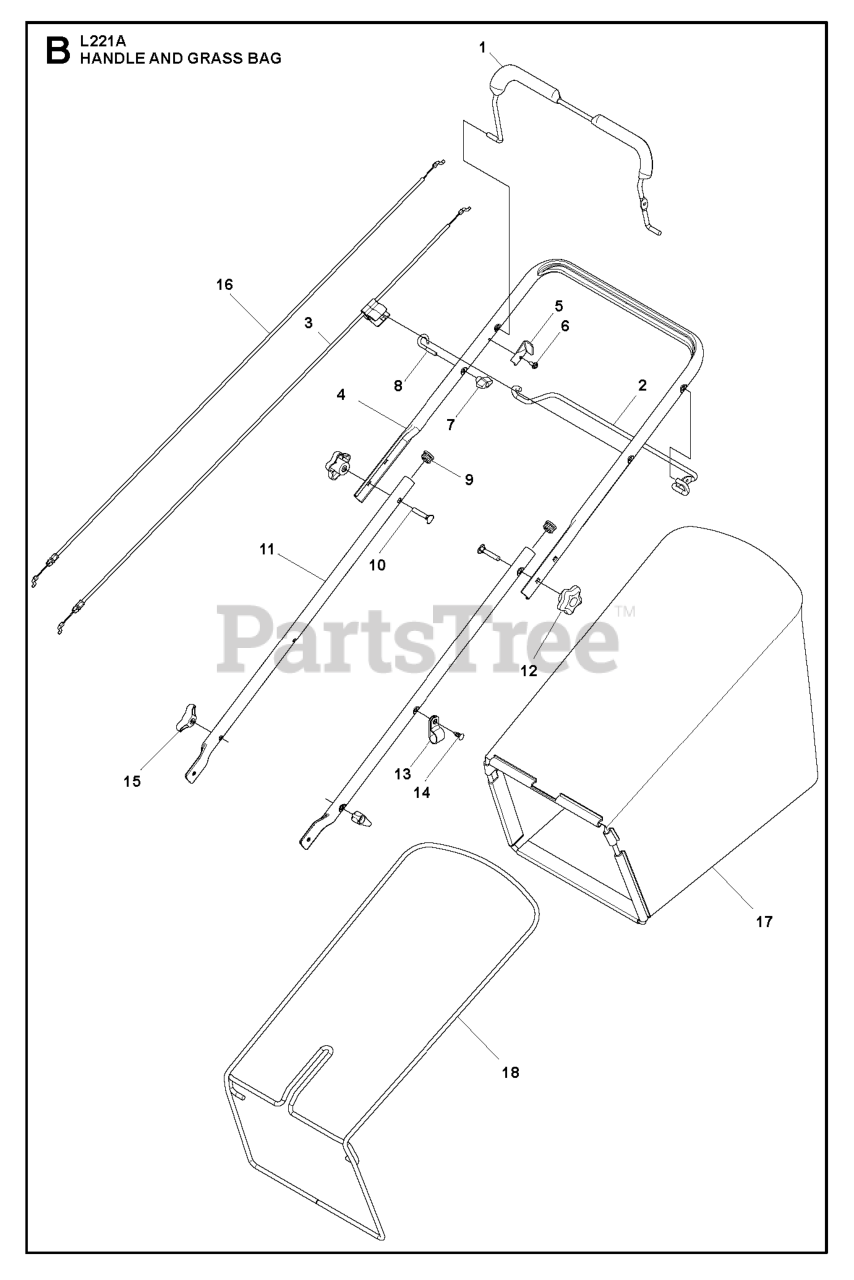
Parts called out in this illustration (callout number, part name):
1	BAIL.ARM.ASSY:STRAIGHT OM
2	BAIL.CONT.DR.S/S.ROUND.BLACK
3	CABLE.MZR.RGD.PLUS.STRT
4	HANDLE.UPP.DST.EXTCR.SM.SP.498
5	BRACKET.UPSTOP.RT
6	SCREW
7	T-KNOB.NEW ROPE GUIDE
8	GUIDE.ROPE.BLK.ZINC.CHROM
9	PLUG.PLASTIC.7/8".14-20.GAUGE
10	BOLT.CONCAVE.HEAD.RETAINING
11	HANDLE.LOW.2PC.2POS.21EFF.498
12	KNOB.HANDLE.PLASTIC.STAR.BLACK
13	CLIP.CABLE.BLK
14	FASTENER.PUSH.O.250X0.783
15	KNOB, DEFLECTOR
16	CABLE.DRIVE.UB.NA.21EFF.AW
17	GBAG.C361029EM.HUSQ.GRY.21EFF
18	FRAME.GBAG.AWD.21.BLACK
